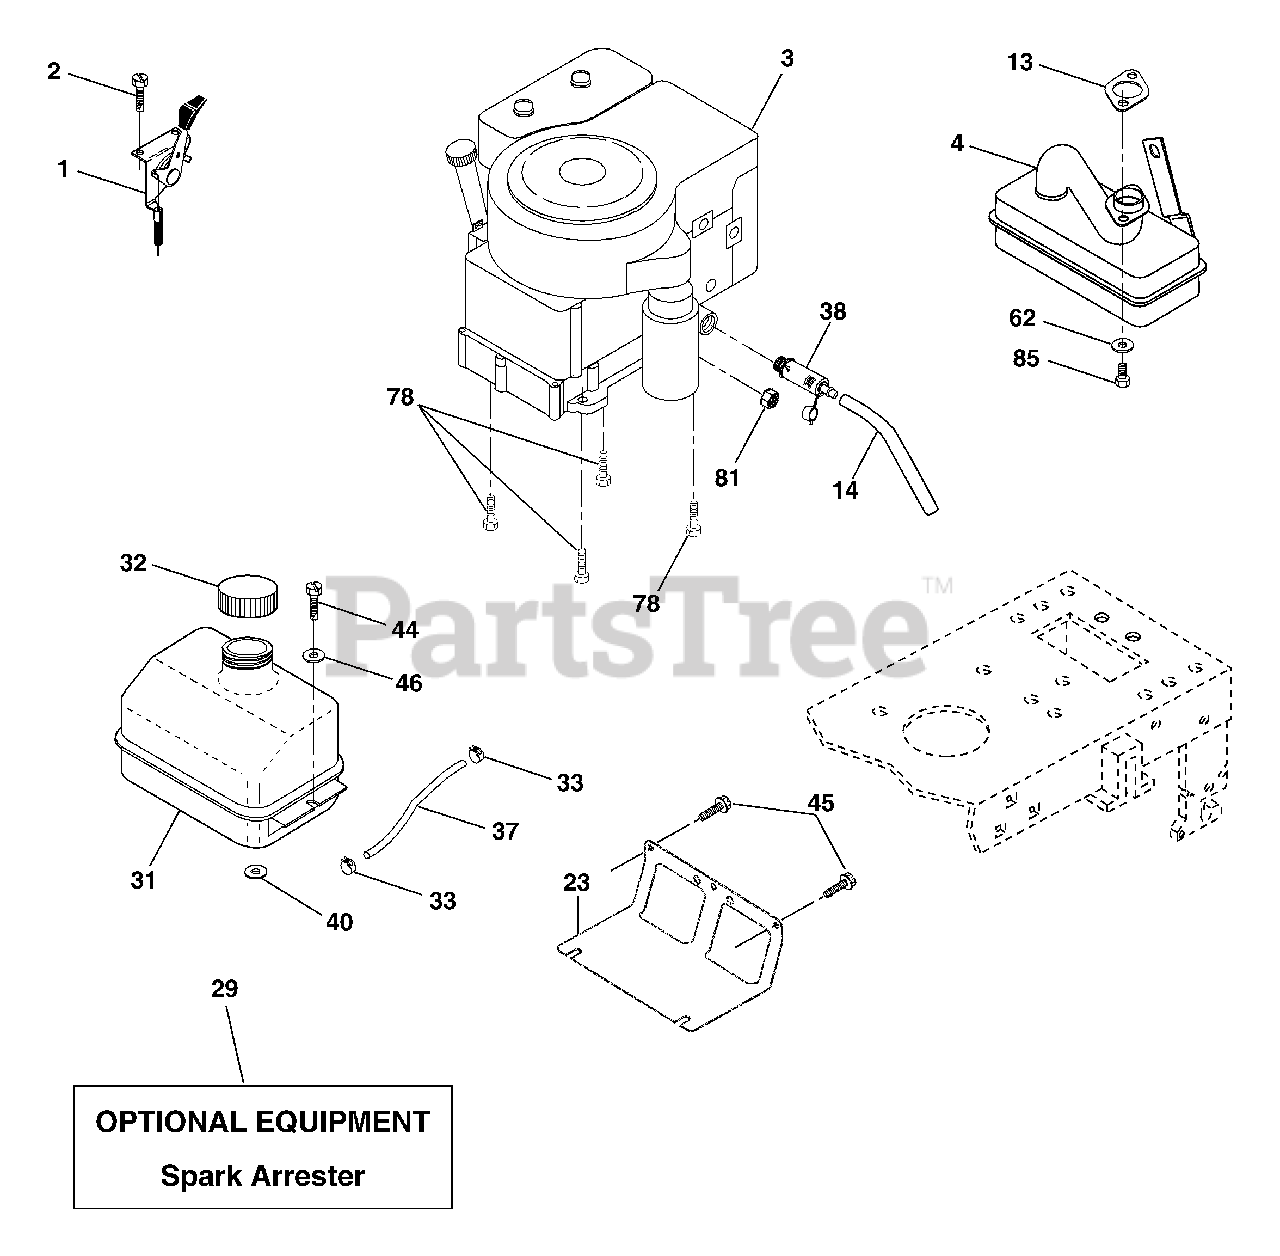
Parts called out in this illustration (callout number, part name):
1	Control Throt /Ch Flag
2	Screw Hex Thd Cut 1/4-20 x 1/2
4	Muffler
13	Gasket Muffler Tec
14	Tube Drain Oil Easy
23	Shield Browning/Debris Guard
29	Arrestor Spark
31	Tank Fuel
32	Cap Asm Fuel W/sym Vented
33	Clamp Hose Blk
37	Line Fuel 20"
38	Plug Drain Oil Easy
40	Bushing
44	Screw Hexwsh Thdrol 1/4-20 x 3/4
45	Screw Hex Wsh Thdrol 3/8-16
46	Washer 9/32 x 7/8 x 16 Ga.
62	Washer Lock 5/16
78	Screw 3/8-16 x 1-1/4
81	Nut Keps Hex 1/4-20 unc
85	Screw
